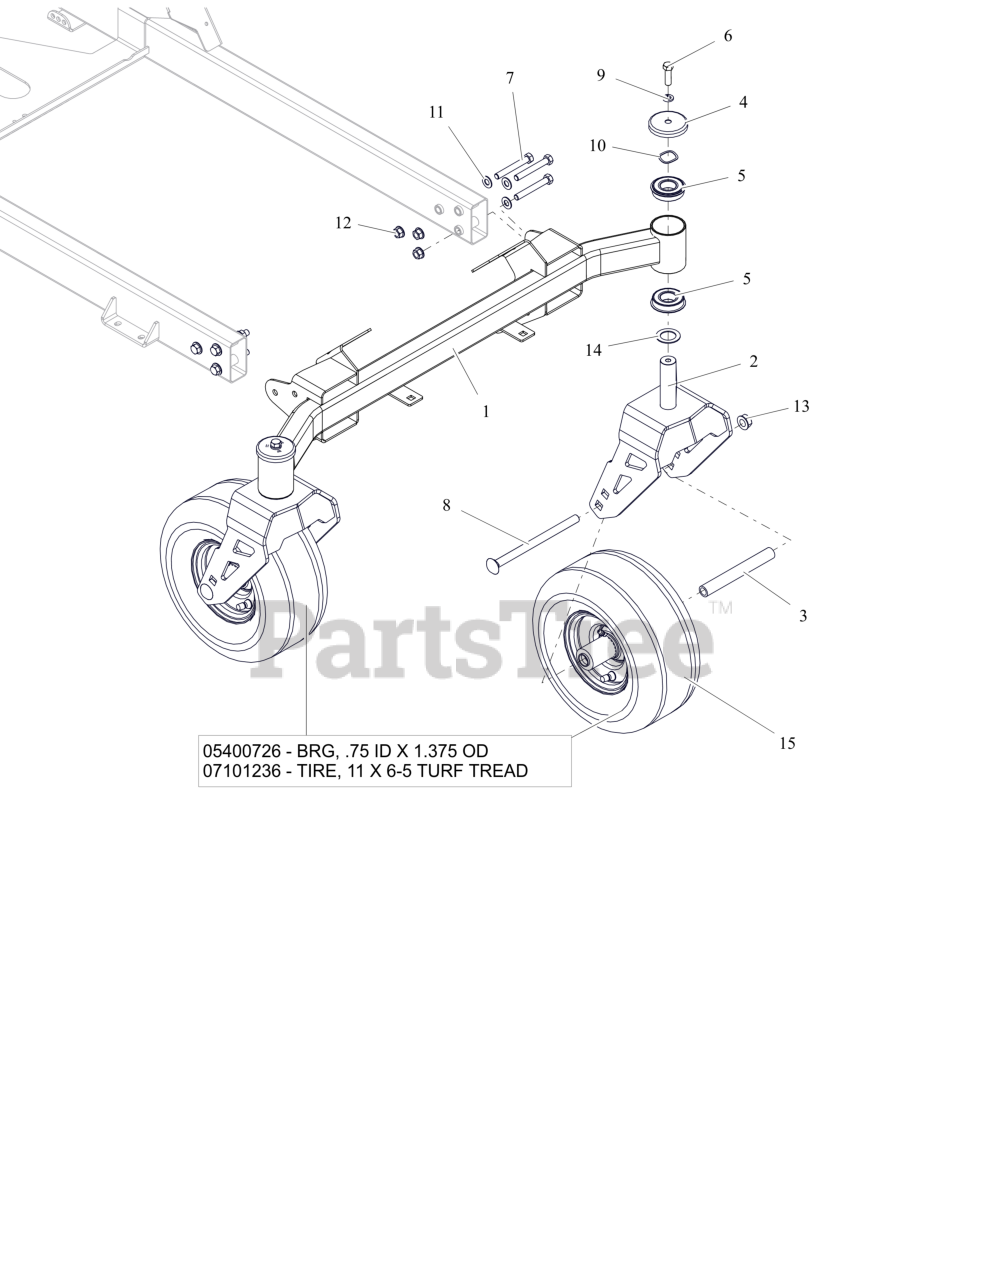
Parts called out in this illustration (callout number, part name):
1	WLDMT- FRONT AXLE
2	WLDMT- CASTOR FORK
3	SPACER, FRONT WHEEL (WIDE 6.0)
4	SHIELD, AXLE BEARING
5	BEARING, BALL -2.000 OD X 1.000 ID X .5625 W/RING
6	BLT, HEX .38-16X1.25 G5 ZCC
7	BLT, HEX .38-16X2.75 G8 ZCC
8	BLT, RHSN .50-13X7.50 G5 ZCC
9	WSHR,LK-REG .375X.094 ZCC
10	WSHR-WAVE 1.0X1.25X.028 .145FH
11	WSHR-FL-STL 0.406X0.812X0.055 HRD
12	NUT-LK-TOP-FLG .375-16 GG ZCC
13	NUT-LK-TOP-FLG .500-13 GF ZCC
14	WSHR-HRD-THRS 1.007X1.542X.062
15	TIRE/WHEEL ASSY 11X6-5
15	BRG, .75 ID X 1.375 OD
15	TIRE, 11X6-5 Smooth
